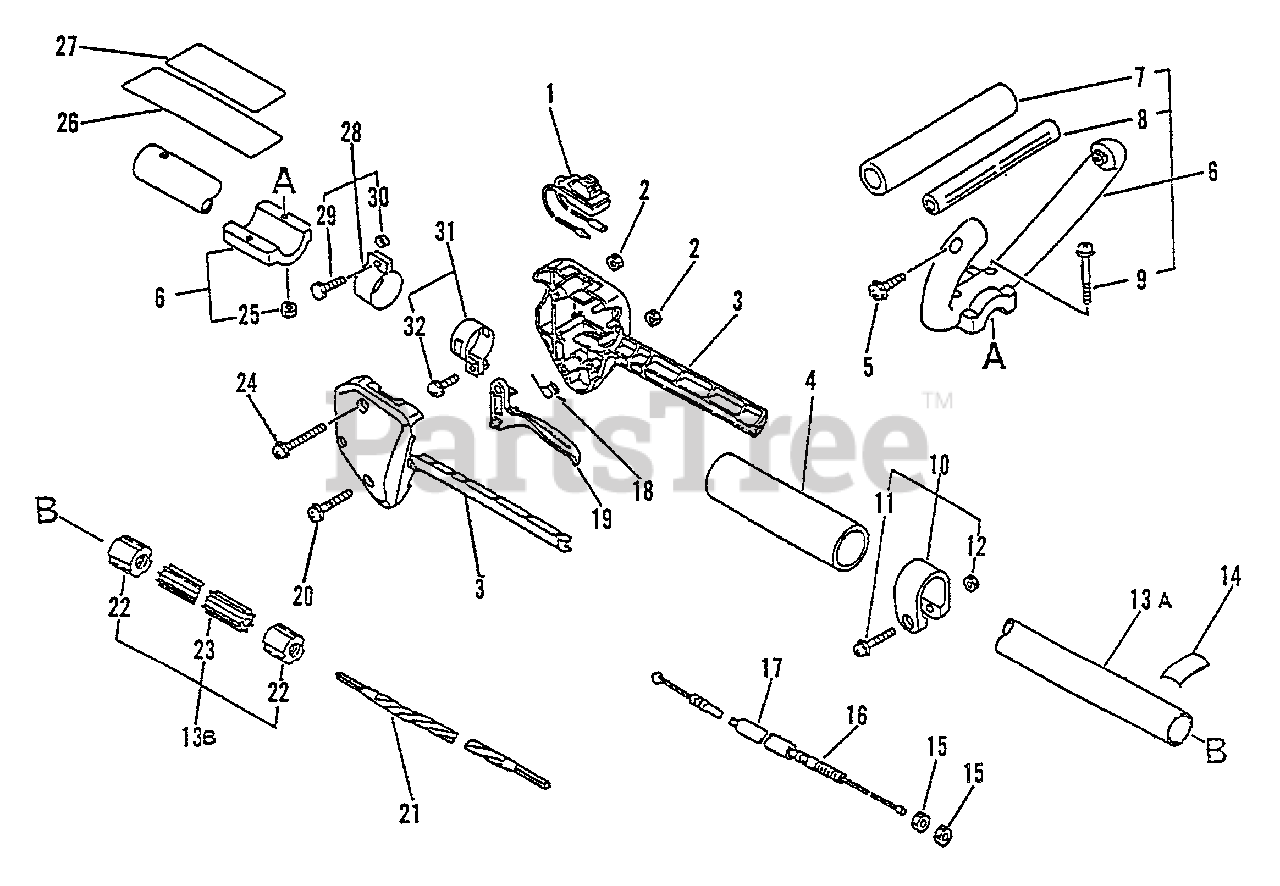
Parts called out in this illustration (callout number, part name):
1	IGNITION SWITCH ASSY
2	NUT M5
3	HANDLE KIT, CONTROL
4	GRIP, HANDLE
5	SCREW 5×30
6	LOOP HANDLE ASSY
7	GRIP, HANDLE
9	SCREW 6×25
10	CLAMP KIT
11	SCREW 5×28
12	NUT M5
13	MAIN PIPE ASSY 25×1500
13A	MAIN PIPE ASSY 25×1500
13B	MAIN PIPE ASSY 25×1500
14	LABEL - ALIGNMENT
16	CABLE, THROTTLE
18	SPRING, TORSION
19	TRIGGER, THROTTLE
20	SCREW 5×25
21	DRIVESHAFT - FLEXIBLE L= 1522
23	LINER, FLEXIBLE 21.6×1420
24	SCREW 5×35
25	NUT, HEX M6
26	LABEL - CAUTION
27	LABEL, CAUTION
28	HOOK
29	BOLT 5×18
30	SPACER, GUARD
31	CLAMP KIT
32	SCREW 5×14
